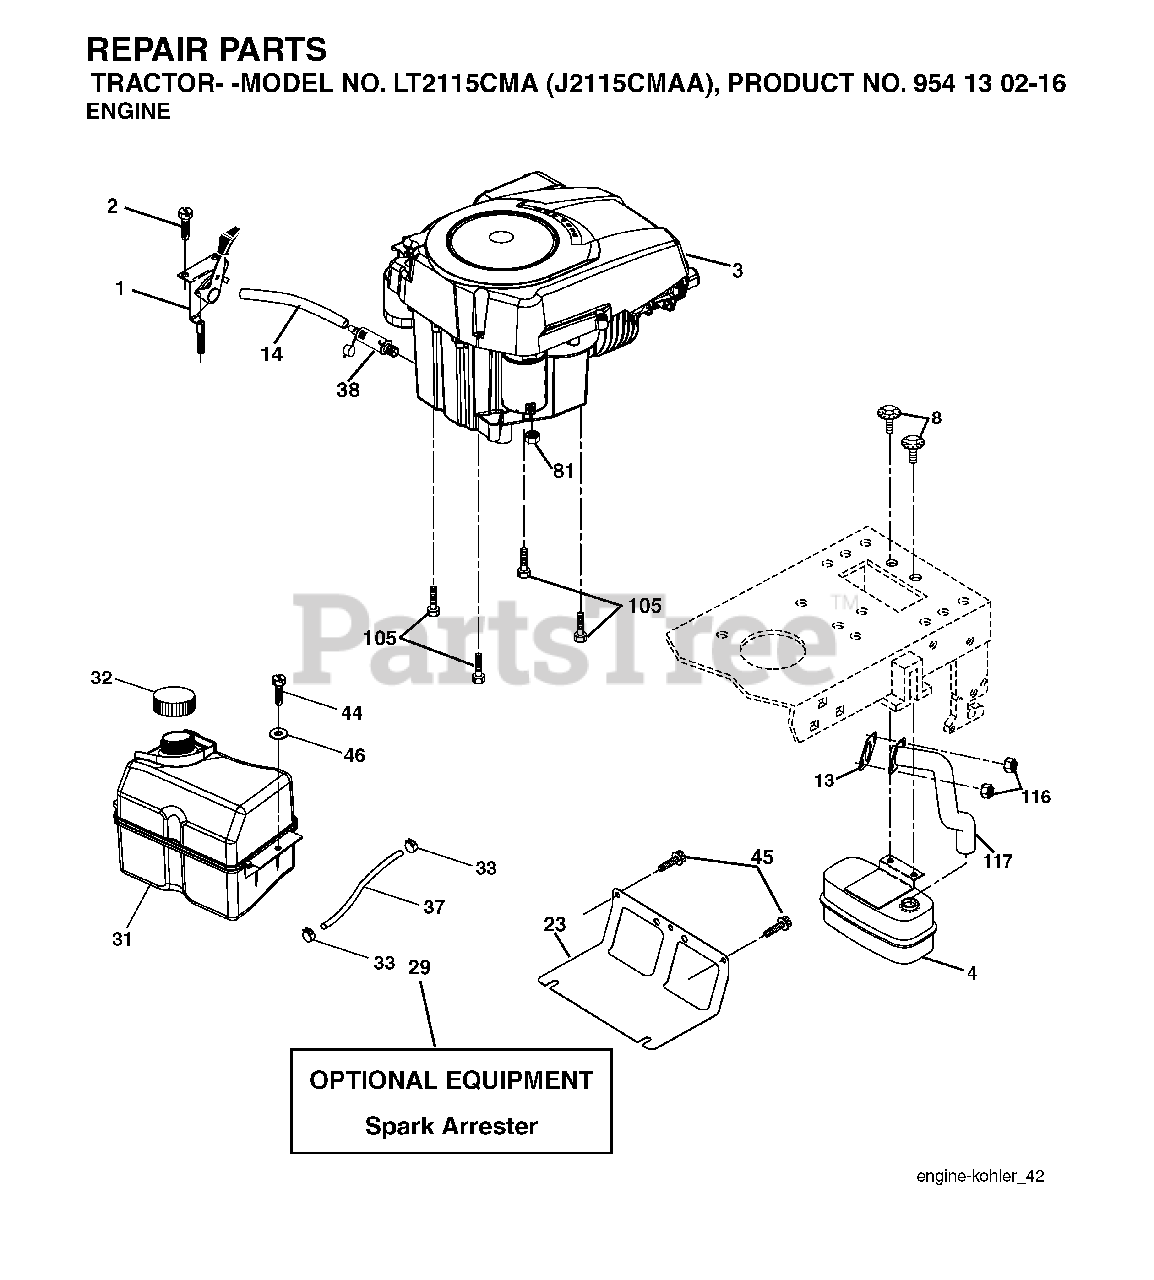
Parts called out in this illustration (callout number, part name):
1	CONTROL.THROTTLE.LT/YT
2	SCREW
4	MUFFLER.SINGLE.CYL.KOHL/B&S
8	BOLT, 5/16-18 X 1 3/4
13	GASKET ENGINE
14	TUBE, DRAIN OIL ASM.
23	SHEILD.BROWNING.DBR.GUARD
29	ARRESTER SPARK (OPTIONAL)
31	TANK FUEL
32	FUEL CAP
33	HOSE CLAMP
37	LINE.FUEL.20
38	PLUG DRAIN OIL EASY
44	SCREW HEXWSHR 1/4-20X3/4
45	SCREW, 3/8-16X3/4
81	NUT
105	SCREW 3/8-16X1
116	NUT.HEX.FLANGE.TOPLOCK
117	TUBE EXHAUST
